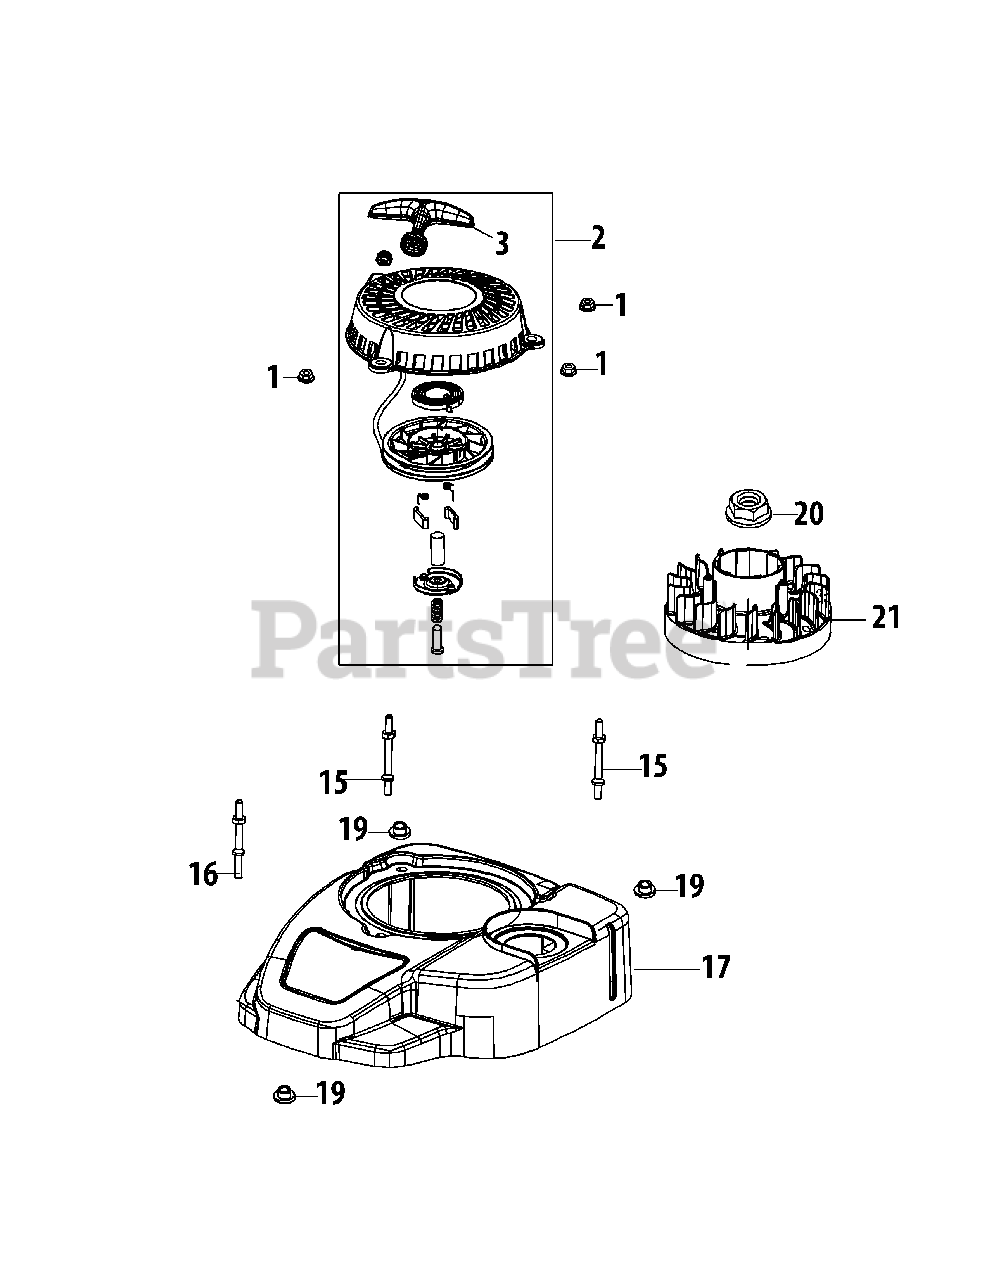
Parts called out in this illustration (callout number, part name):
1	Nut M6X10Mm Starter/Carb/Muff
2	Starter Recoil Assembly
3	Starter Handle
15	Starter/Shroud Rear Stud M6×75
16	Starter/Shroud Front Stud M6×73
17	Engine Shroud Assembly
19	Engine Shroud Spacer
20	Flywheel Nut M14
21	Flywheel
